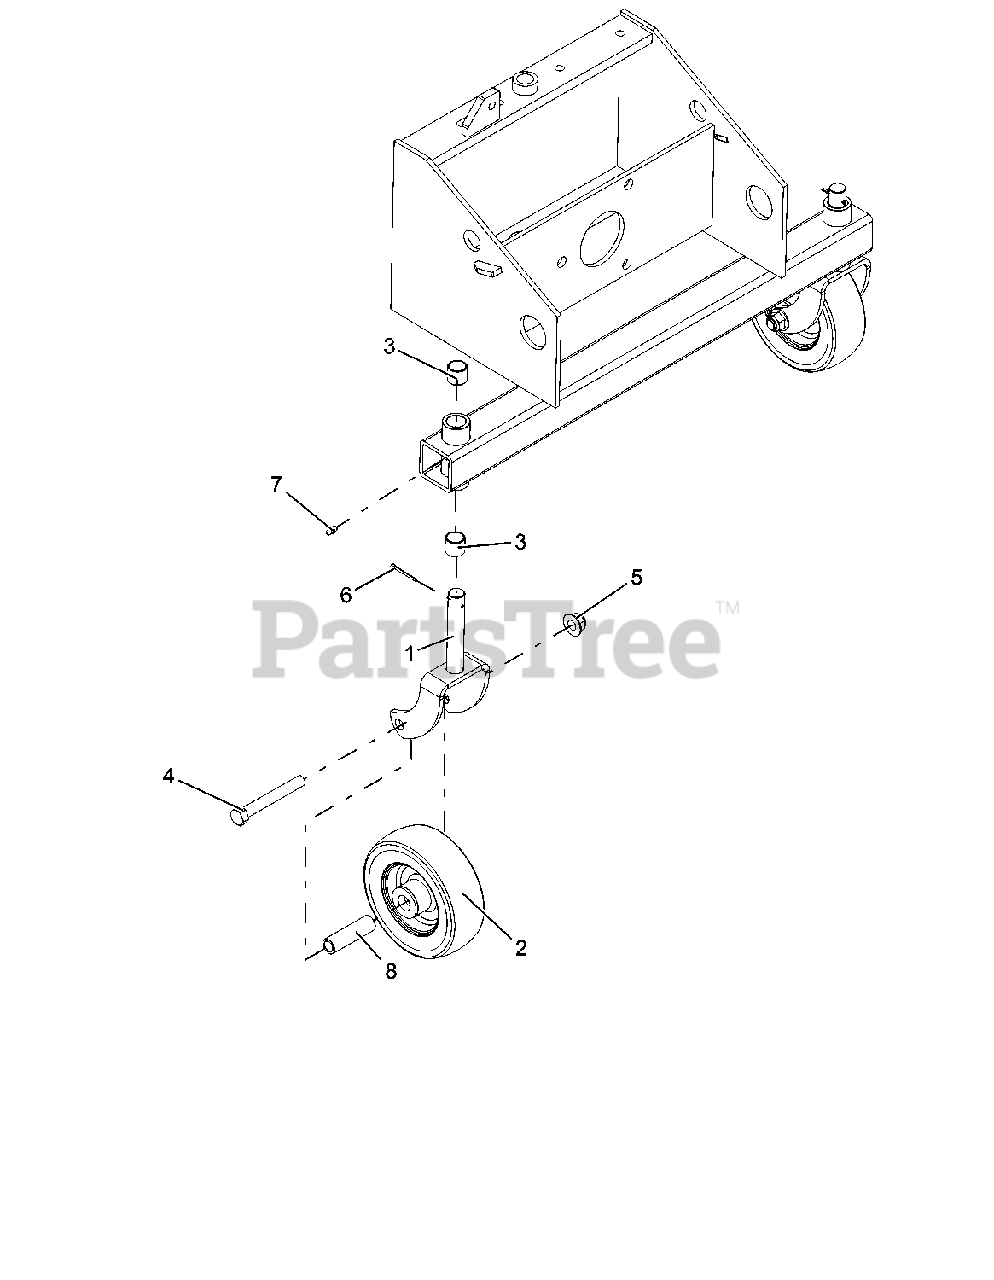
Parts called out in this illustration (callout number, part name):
1	WLDMT, CASTER FORK
2	WHL-CASTER
3	BSHG-SLV .752X.877X.75 BRONZE
4	BLT,HEX .50-13X3.75 G5ZC120
5	NUT,LK-NYL-FLG .50-13 G5ZC120
6	PIN,CTR.12X1.25EXTPRSQCT ZC120
7	FTG-LUBE .25-28X.256 SST
8	BUSH.,S.516X.745X2.59 ST
